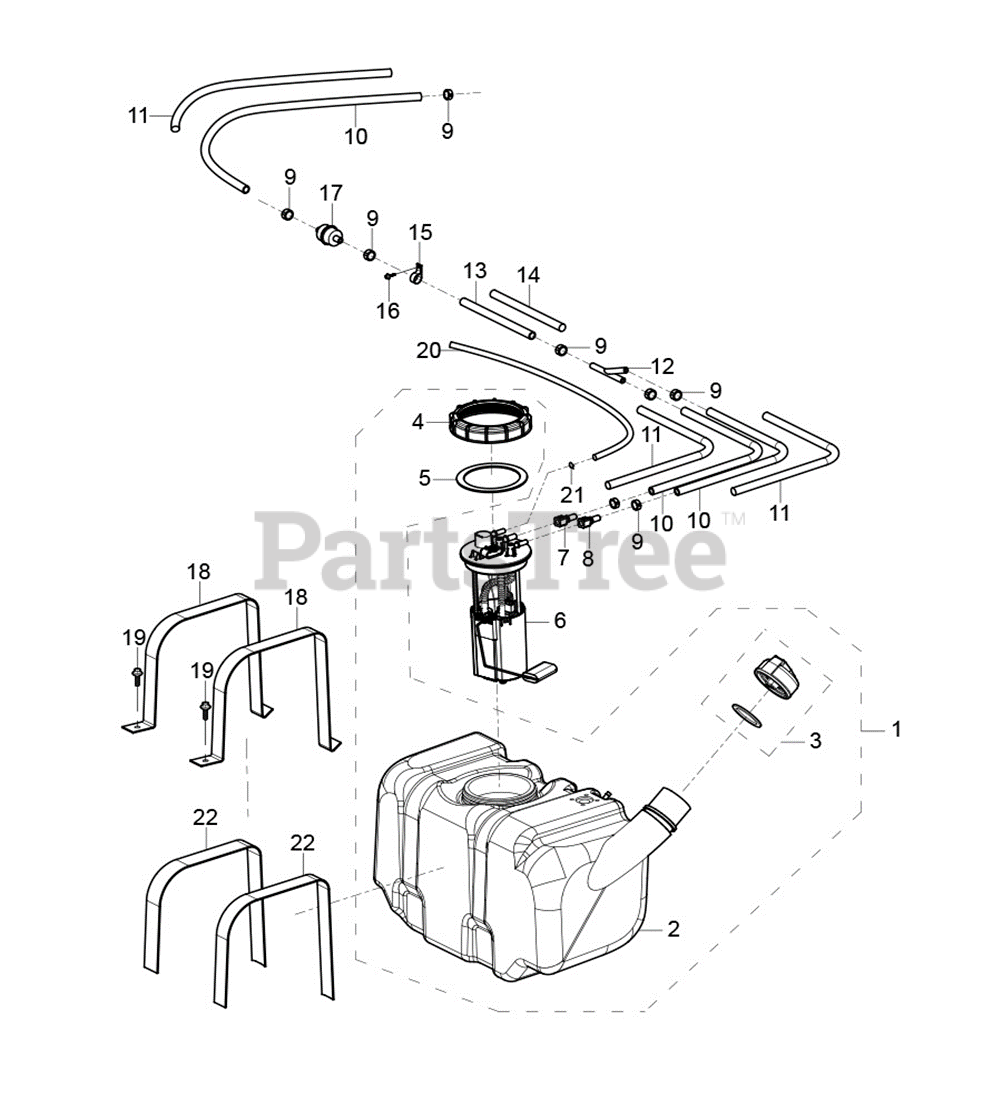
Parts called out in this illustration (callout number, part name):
1	FUEL TANK ASSEMBLY
2	FUEL TANK BODY
4	FUEL PUMP RETAINING CAP
5	SEAL GASKET-FUEL PUMP EFI ENG
6	FUEL PUMP
7	PLUG-FUEL OUTLET EFI ENGINE
8	FUEL INLET CONNECTOR
9	PRESSURE CLAMP A
10	FUEL LINE - 0.05MPA I
11	THERMAL INSULATIONBELLOWS
12	FUEL PIPE - 3 WAY
13	FUEL LINE - 0.05MPA III
14	HEAT INSULATION HOSE III
15	BRAKE LINE CLIP I
16	HEXAGON FLANGE BOLT M6X16
17	FUEL FILTER
18	FUEL TANK HOLDDOWN
19	FLANGE BOLT M8X25
20	FUEL LINE - 7 x 11 x 700
